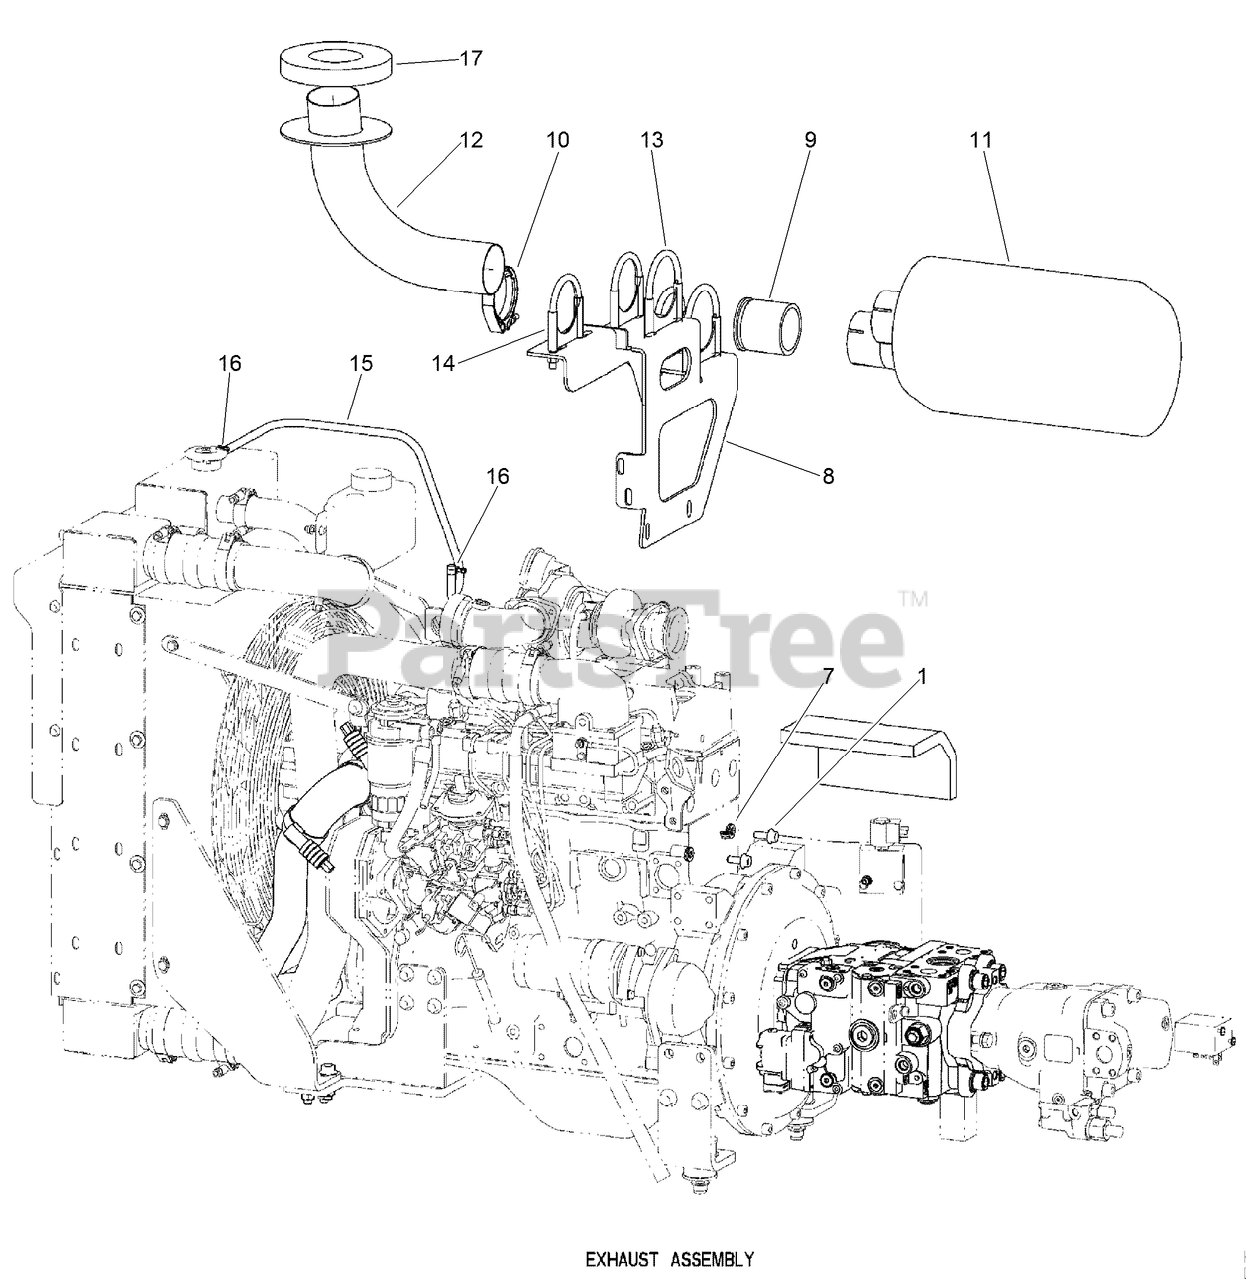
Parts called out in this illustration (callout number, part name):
1	SCREW-FLANGE
7	WASHER-FLAT
8	ASSEMBLY - Muffler Mount
9	FLANGE-ADAPTER, TURBO
10	CLAMP - T-Bolt
11	ASSEMBLY - Muffler
12	TUBE-EXHAUST (W/ SEAL PLATE)
13	CLAMP-GUILLOTINE
14	CLAMP-GUILLOTINE
15	OVERFLOW LINE - 3/8 ID x 32 Length
16	CLAMP - Hose Type M # 06
17	INSULATION
